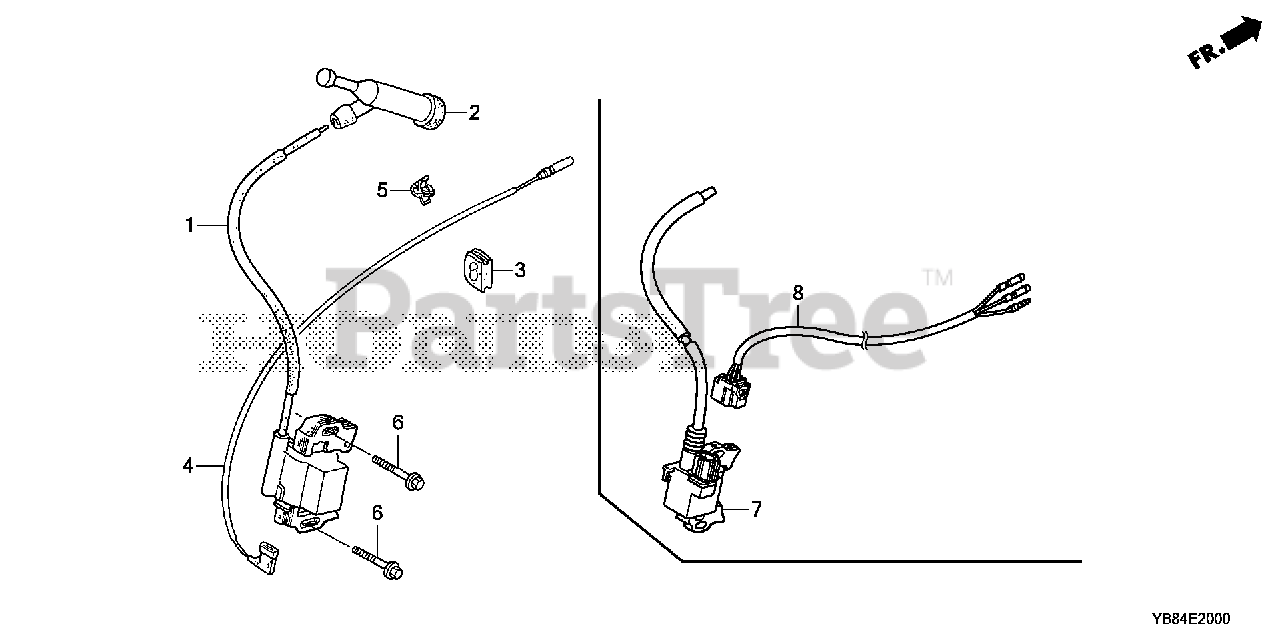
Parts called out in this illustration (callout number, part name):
1	COIL ASSY., IGNITION
2	CAP ASSY., NOISE SUPPRESSOR (NICHIWA Y-EZ RTFM256)
3	GROMMET, WIRE
4	WIRE, STOP SWITCH (370MM)
4	WIRE, STOP SWITCH (NOT AVAILABLE)
5	HOLDER, STOP SWITCH WIRE
6	BOLT, FLANGE (6X28) (CT200)
